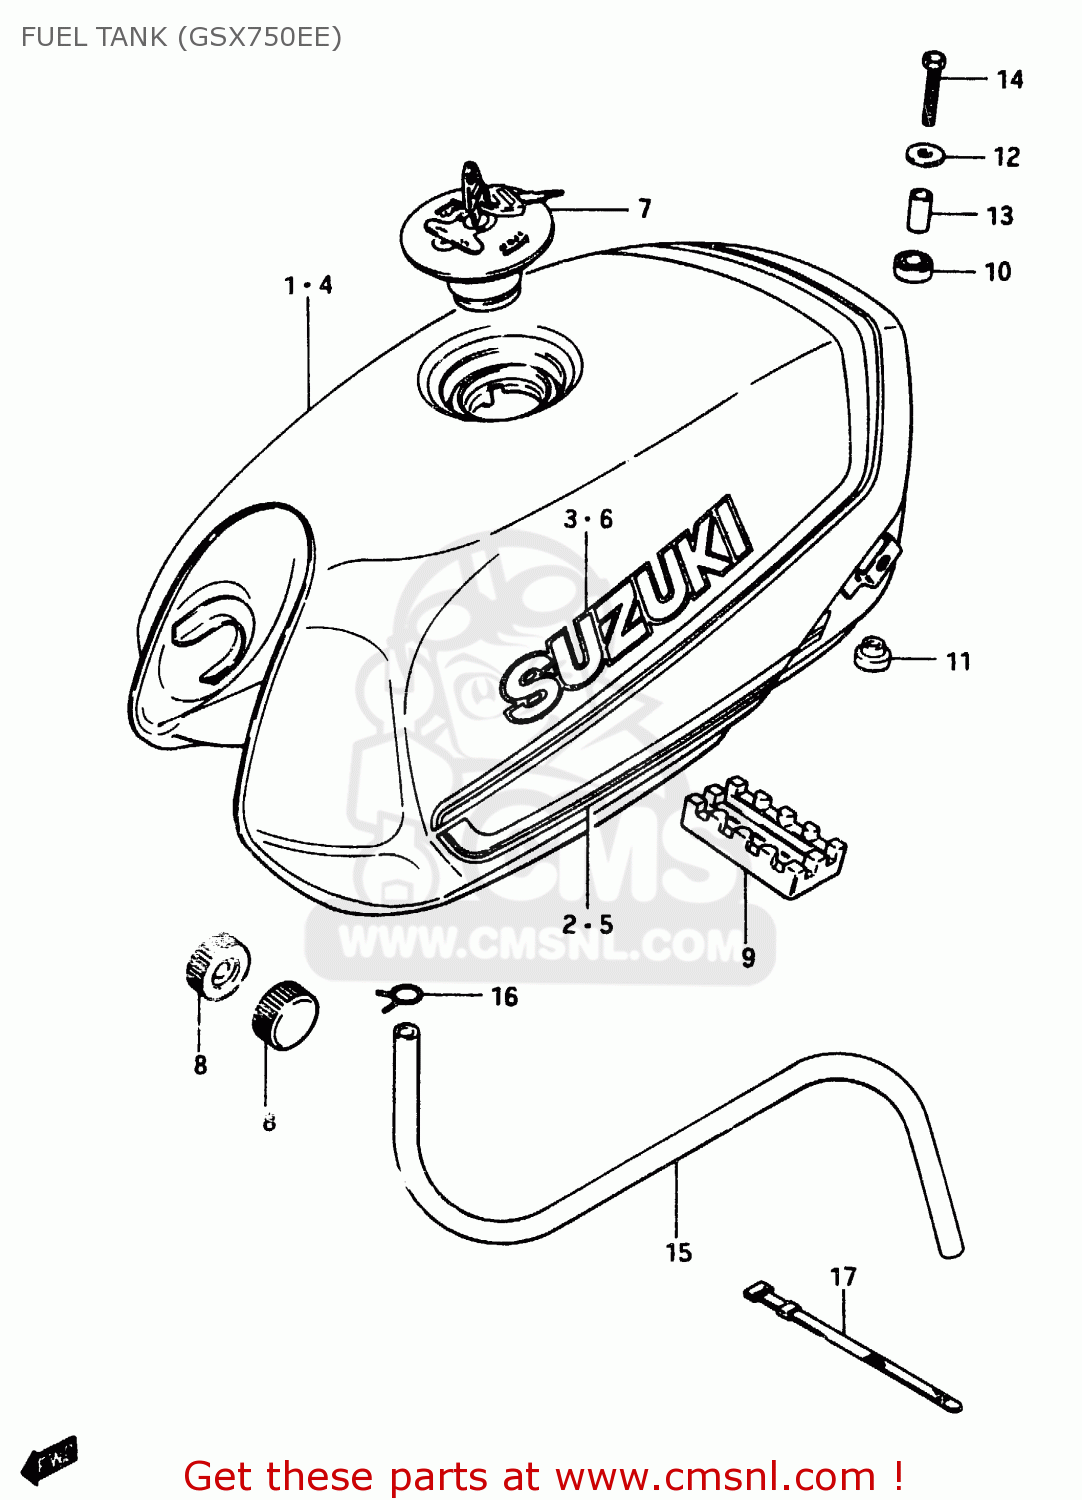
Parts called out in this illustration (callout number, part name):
1	TANK, FUEL (BLUE)
2	TAPE SET, FUEL TANK
3	EMBLEM
4	TANK, FUEL (RED)
5	TAPE SET, FUEL TANK
6	EMBLEM
7	CAP, FILLER
8	CUSHION
9	CUSHION,FUEL TANK CTR
10	CUSHION
11	CUSHION
12	WASHER (6.5X24X1.6)
13	SPACER
14	BOLT
15	HOSE,FUEL
16	CLIP
17	CLAMP(L:187)
